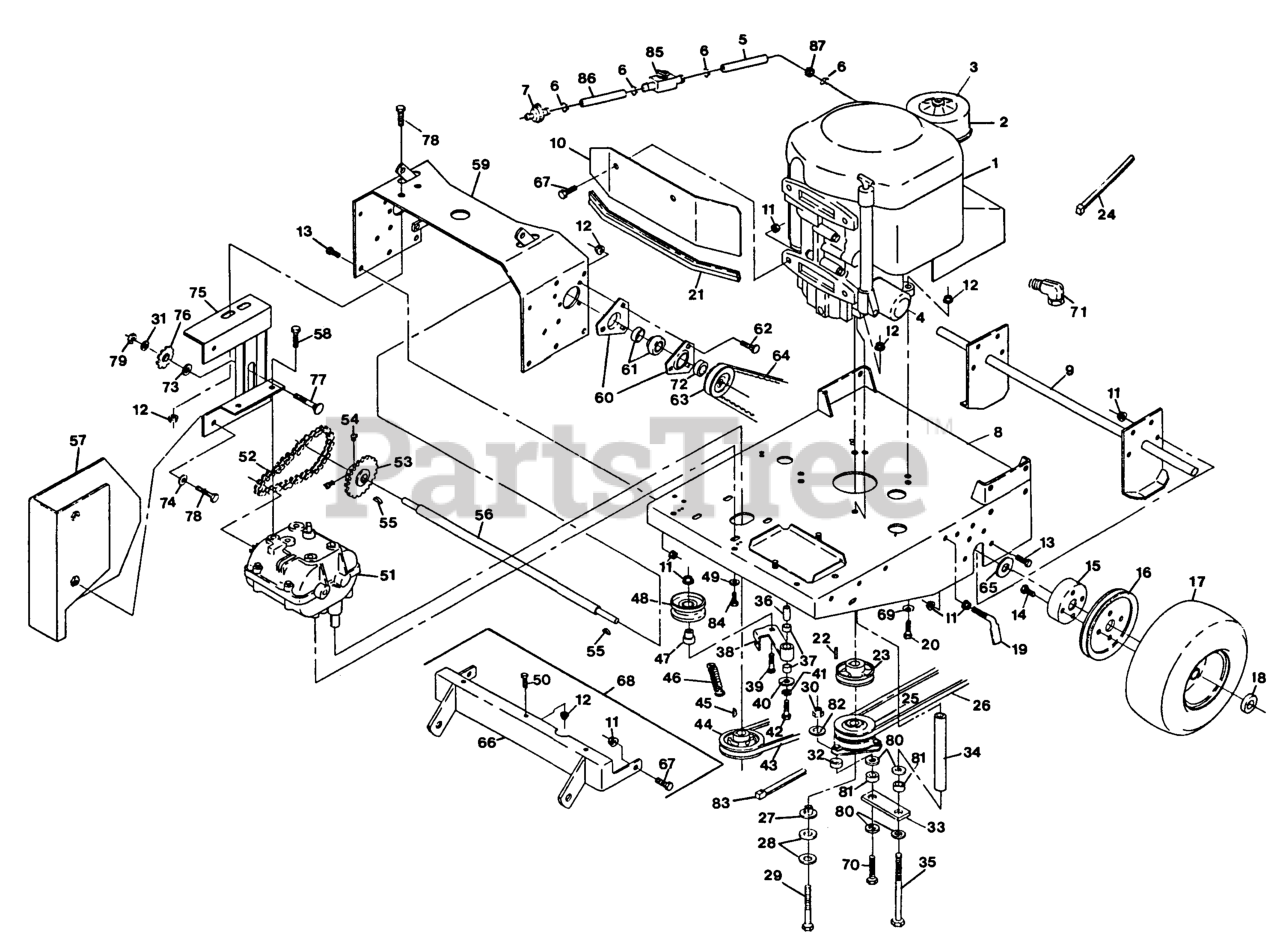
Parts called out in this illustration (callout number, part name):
5	HOSE-LINE, FUEL
6	CLAMP
10	SHIELD-HEAT, TRACER
14	SCRW,TPTTE HH
19	SCRAPER
24	TIE-CABLE
26	BELT,DECK DRIVE
27	BUSHING,CLUTCH KEEPER
28	WASHER-SPRING
35	SCREW-HH
36	BUSHING
37	SLEEVE-BEARING
46	SPRING-EXTENSION
47	BUSHING-IDLER
52	CHAIN-#40 ROLLER
60	HOUSING-FLANGE
64	BELT WHL CLTCH W-4.2
66	WLD,SULKY HITCH
68	Hitch - Tracer Sulky
69	WASHER-SPRING
71	FITTING-ELBOW-90
74	WASHER-LOCK
81	SPACER,CLUTCH ANCHOR
83	TIE-PLASTIC
85	VALVE-FUEL
86	HOSE-LINE, FUEL
87	CLAMP-HOSE
